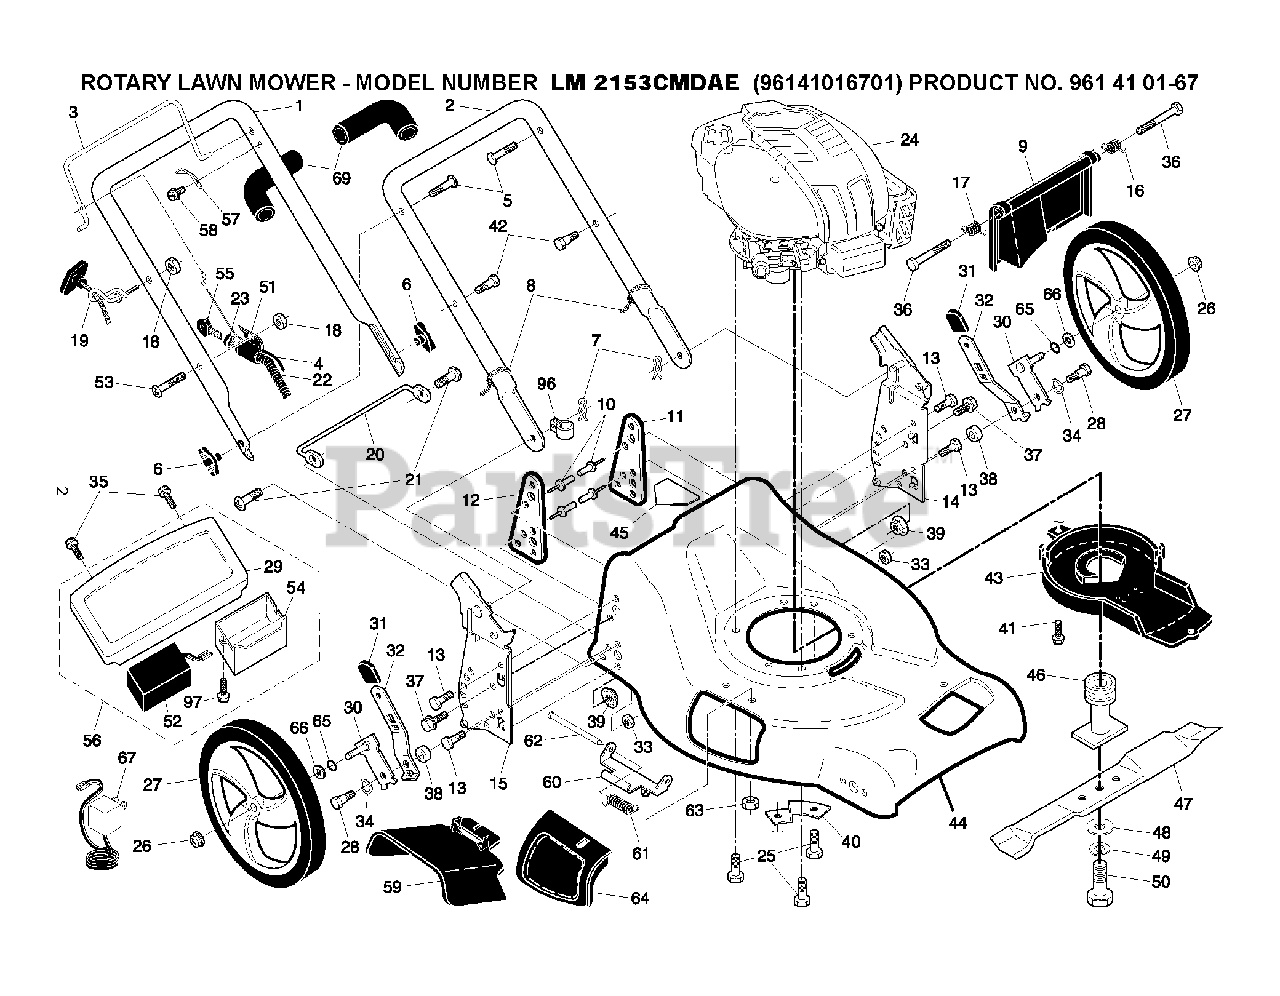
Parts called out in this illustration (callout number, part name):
4	CABLE, OPERATOR PRESENCE
5	BOLT, HANDLE 5/16-18X1.75
6	KNOB, DEFLECTOR
7	HAIRPIN COTTER
8	TIE GUIDE
9	REAR DOOR ASSEMBLY
10	RIVET BLIND
11	SUPPORT BRACKET LH
12	BRACKET.SUPRT.RH.21.FWGD
13	SCREW 14-20 X 5/8
14	HANDLE BRACKET ASSEMBLY, LEFT
15	HANDLE BRACKET ASSY. (RIGHT)
16	SPRING.REAR.DOOR.EZ.21.LT
17	SPRING.REAR.DOOR.EZ.21.RT
18	NUT
19	GUIDE.ROPE.STD.BLK.ZIN
21	SCREW
22	WIRING HARNESS
23	NUT.CAP.SNAP-ON.KEY START
25	BOLT 3/8-16X1-1/8
26	NUT.HEX.FLANGE.3/8-16.LOCKNUT
28	SHOULDER BOLT 5/16-18
29	PANEL.TRIM.21.FWGD.ES
30	ARM.ASM.AXLE.REAR.5/9.POS.BZP
31	SELECTOR KNOB
32	SELECTOR SPRING
33	NUT.71038.31-18.HEX.NYLOCK
34	WASHER FLAT
35	SCREW.PAN.HEAD.#10
37	BOLT
38	SPACER.HEIGHT.ADJUSTER
39	NUT.FLANGE.5/16
40	BRACKET
41	SCREW.HEX.WSH
42	SCREW.SHOULDER.HH.10X.281X.6
43	DEBRIS SHIELD
45	DECAL.INTERNATIONL.CUTFINGER
47	BLADE.21.PUSH
48	WASHER,HARDEN
49	LOCKWASHER
50	SCREW, HEX HD 3/8-24 X 1-3/8
51	KEY.START.CONTROL.W/ZONE
52	BATTERY.AMP.CONNECTOR
53	SCREW.(COMBINATION CONTROL)
54	BOX.BATTERY.TRIM
55	KEY.MOLDED
56	PANEL.ASM.TRIM/BATTERY.BOX
57	BRACKET UPSTOP
59	DISCHARGE DEFLECTOR
60	HINGE BRACKET ASSEMBLY
61	SPRING.TORSION
62	ROD.HINGE.21
63	LOCKNUT
64	DOOR.MULCH.21.REAR
65	O-RING..070X.487.NEOPRENE
66	WASHER PM
69	GRIP.HANDLE.FOAM.WIDE.(1 SIDE)
96	CLIP.CABLE.BLK
